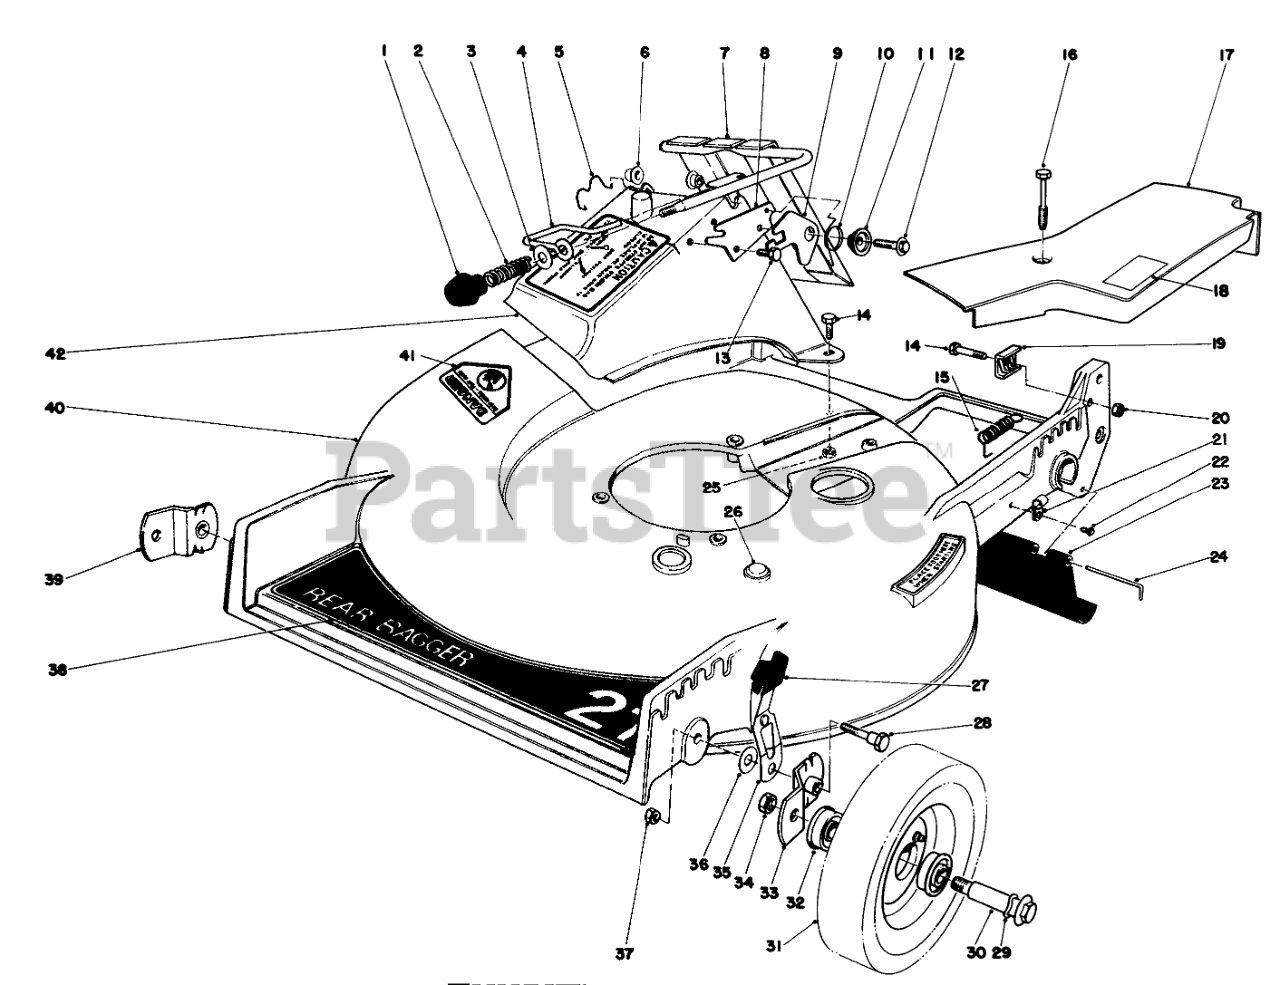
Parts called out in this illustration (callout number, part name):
2	COMPRESSION SPRING
3	WASHER-FLAT
4	DOOR LATCH
5	DOOR RETAINER
6	BUSHING-NYLON
7	DOOR & HANDLE WA
8	DOOR LATCH PLATE
9	Latch-Door
10	TORSION SPRING
11	Latch Spacer
12	Screw
13	SCREW-HWH
14	SCREW-HH
15	IDLER SPRING
16	SCREW-HHFTF
17	Belt Cover
18	Sticker Grease
19	CLAMP-CABLE
20	NUT-JAM
21	CLAMP-NYLON
22	SCREW-HWH
23	SHIELD - TRAILING
24	Rod Shield
25	NUT-LOCK, NI
27	KNOB-ARM
28	PIVOT SCREW
29	SPRING WASHER
31	Wheel & Tire Assembly (Incl. Ref. #32)
32	BEARING-BALL
33	PIVOT ARM ASM A
34	Nut
35	SPRING ARM ASM (R&S)
36	WASHER-PIVOT
37	Nut
38	Decal-Deck
39	PIVOT ARM ASM B
40	Housing
41	DECAL-DANGER
42	DISCHARGE CHUTE B
